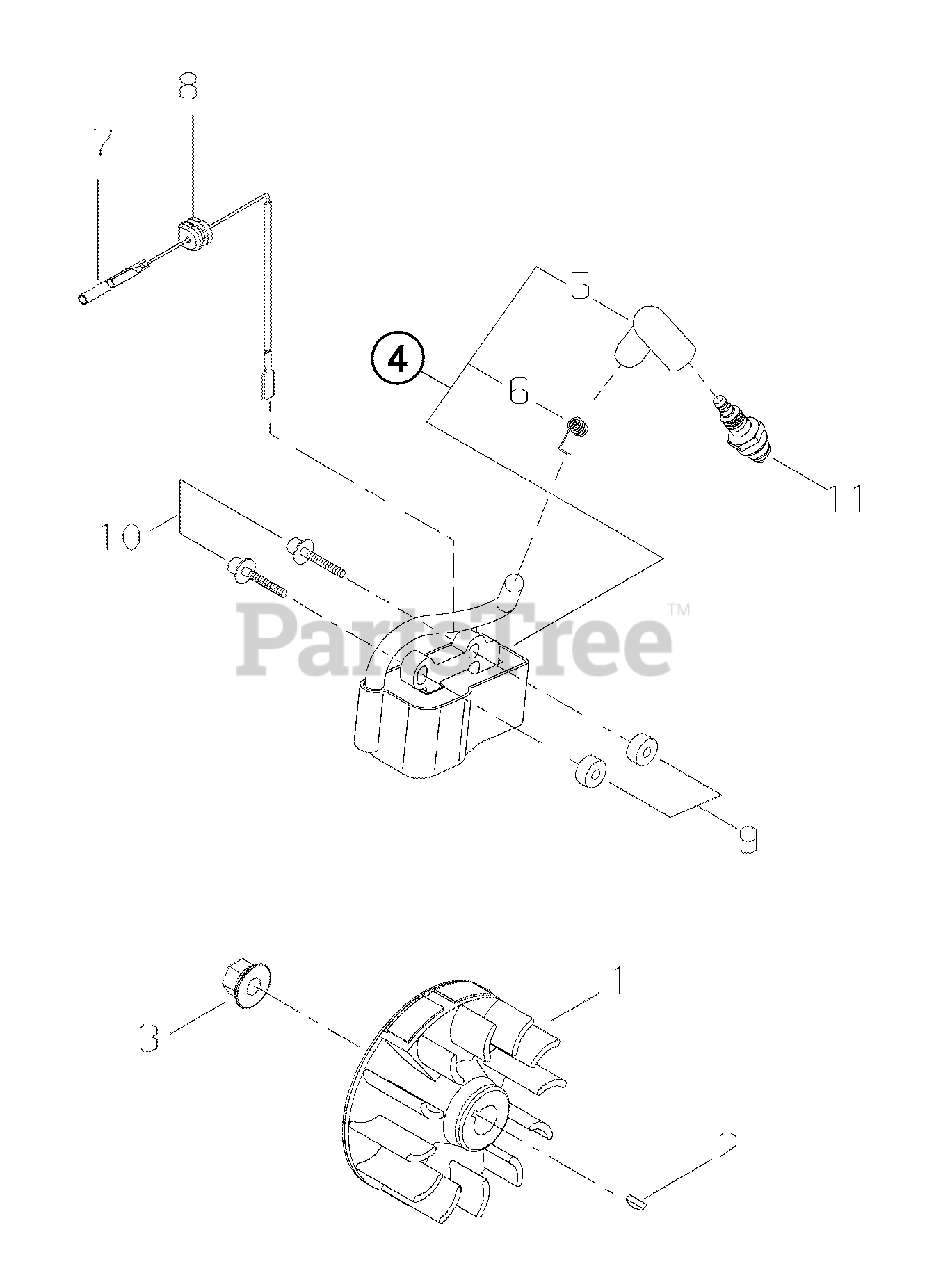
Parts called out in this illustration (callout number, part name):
1	FLYWHEEL
2	KEY, WOODRUFF 3×10
3	NUT M8
4	COIL ASSY, IGNITION
5	CAP, SPARK PLUG
6	TERMINAL, SPARK PLUG
7	LEAD - IGNITION
8	GROMMET, LEAD
9	INSULATOR 4.2×11×6
10	BOLT M4×26
11	SPARK PLUG - CMR5H
